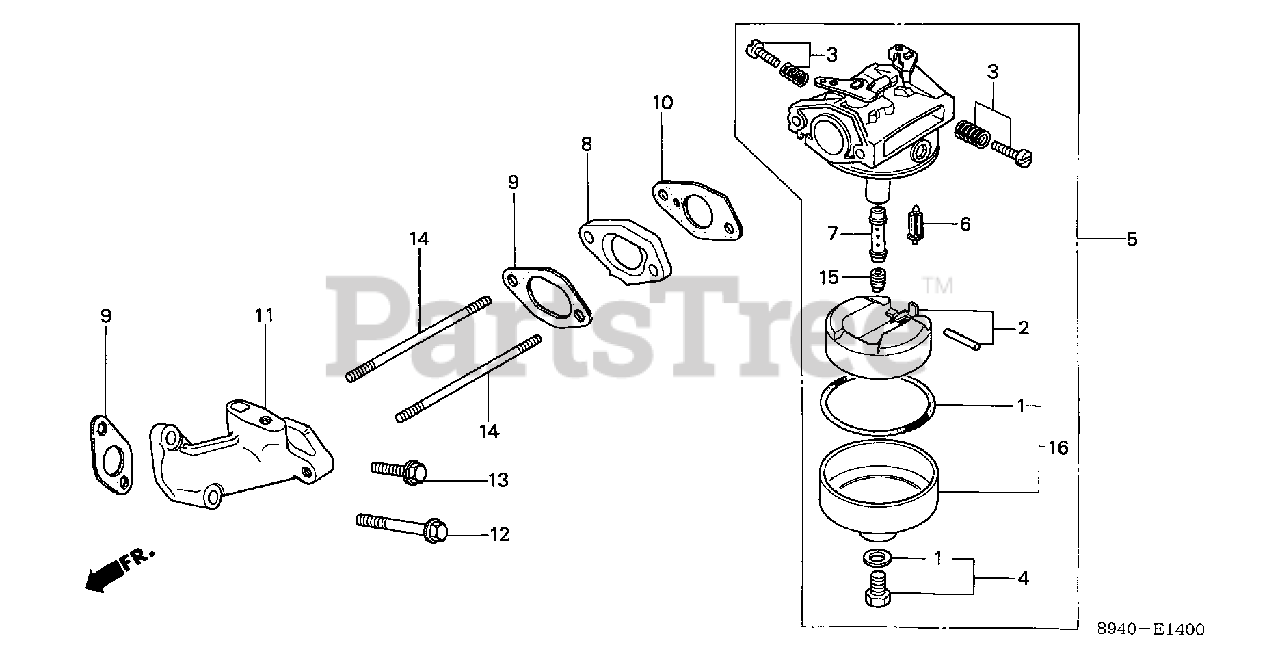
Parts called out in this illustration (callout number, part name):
1	GASKET SET (CARBURETOR NO.)
3	SCREW SET A (CARBURETOR NO.)
3	SCREW SET A
3	SCREW SET A (CARBURETOR NO.) (NOT AVAILABLE)
4	SCREW SET
5	CARBURETOR ASSY. (BB31A C) (CARBURETOR NO.)
5	CARBURETOR ASSY. (BB31A C)
6	VALVE, FLOAT
7	NOZZLE, MAIN (NOT AVAILABLE)
8	INSULATOR, CARBURETOR
9	GASKET, INSULATOR
10	GASKET, CARBURETOR
11	MANIFOLD, IN.
12	BOLT, FLANGE (6X50)
13	BOLT, FLANGE (6X20) (CT200)
14	BOLT, STUD (6X141) (NOT AVAILABLE)
15	JET, MAIN (#65)
15	JET, MAIN (#68)
15	JET, MAIN (#70)
15	JET, MAIN (#72)
15	JET, MAIN (#75)
16	CHAMBER SET, FLOAT
